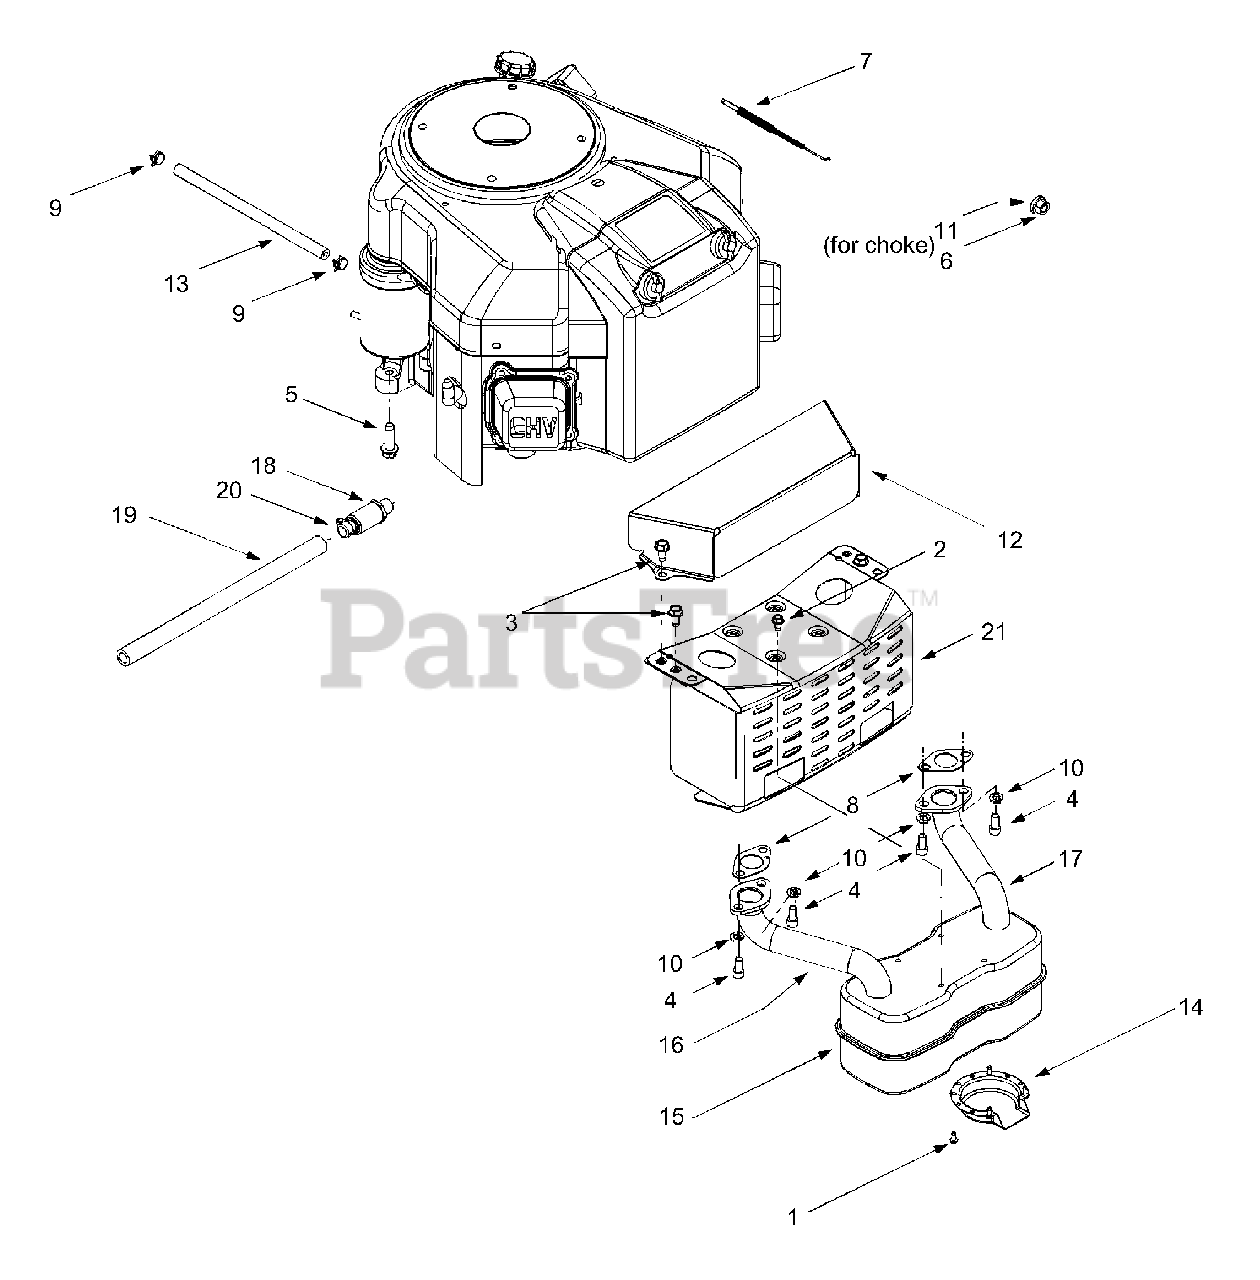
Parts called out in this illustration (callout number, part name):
1	Screw, #8-18 x .5
2	Self-tapping Screw, 1/4-20 x .5
3	Self-tapping Screw, 5/16-12 x .75
4	Socket Cap Screw, 5/16-18 x .625
5	Self-tapping Screw, 3/8-16 x 1.25
6	Hex Nut, 3/8-16
7	Throttle Cable
8	Exhaust Gasket
10	Lock Washer, 5/16
11	Lock Washer, .406 x .875 x .059
12	Engine Heat Shield
13	Fuel Line Hose
14	Muffler Deflector
15	Muffler, Twin Inlet
16	RH Exhaust Pipe
17	LH Exhaust Pipe
18	Oil Drain Valve
19	Oil Drain Hose
20	Oil Drain Cap
